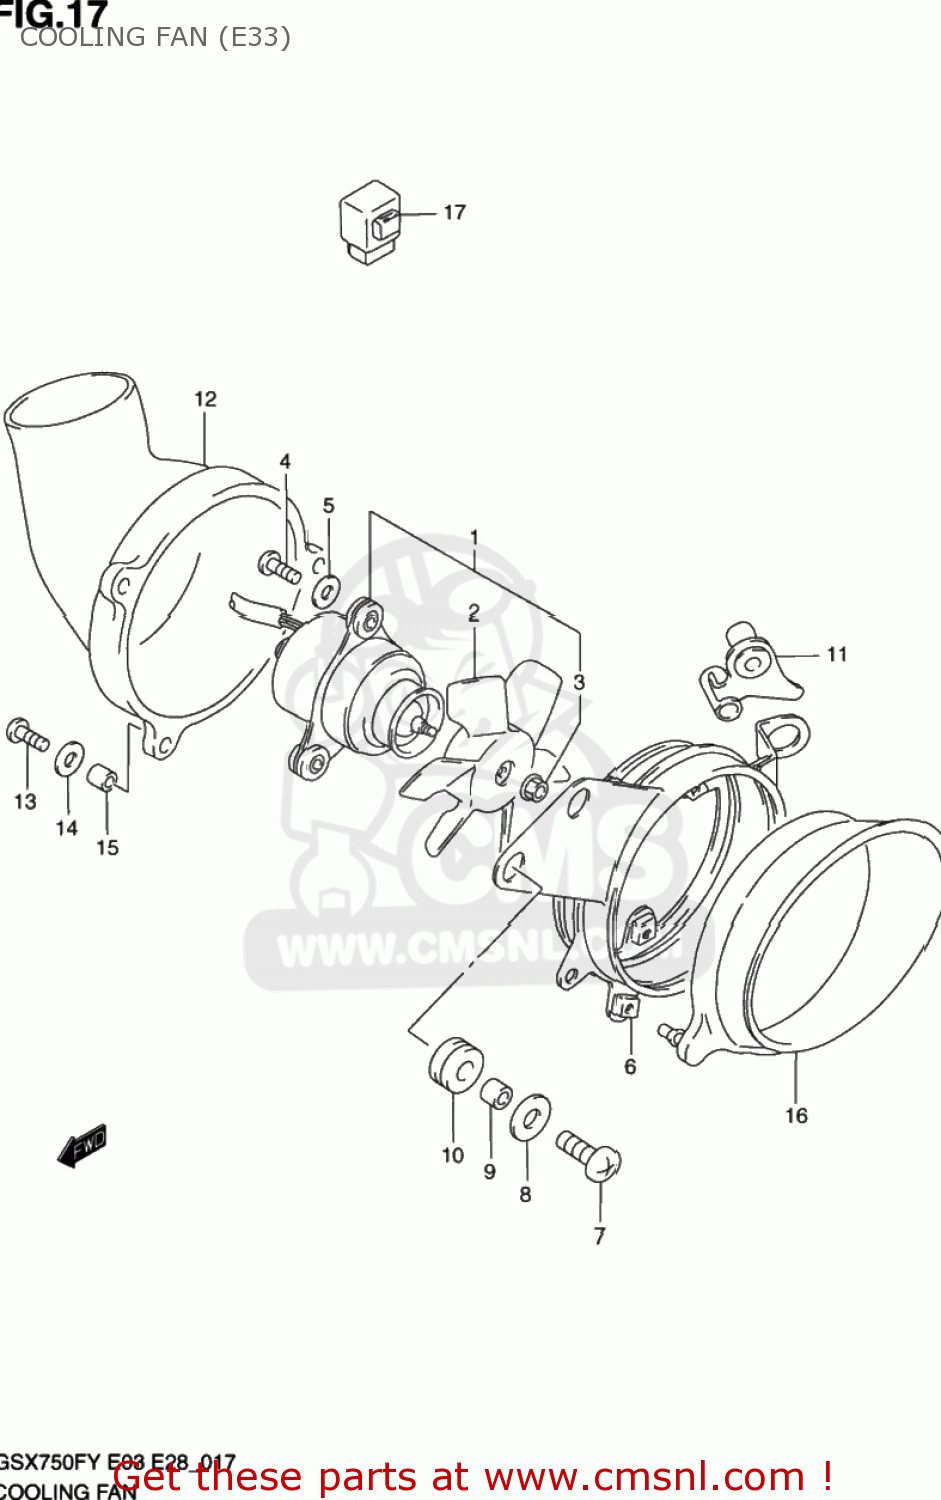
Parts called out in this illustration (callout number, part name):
1	FAN ASSY,COOLING
2	FAN
3	NUT
4	SCREW 4X16
5	WASHER(4.3X14X0.8)
6	SHROUD,FAN
7	SCREW
8	WASHER(6.5X18X1)
9	SPACER(6.5X9X6.5)
10	CUSHION
11	BRACKET,FAN SHROUD
12	DUCT,FAN COOLING NO.1
13	SCREW
14	WASHER(4.3X14X0.8)
15	SPACER(4.5X6.5X5)
16	DUCT,FAN COOLING NO.2
17	CONTROLLER ASSY,FAN MOTOR
